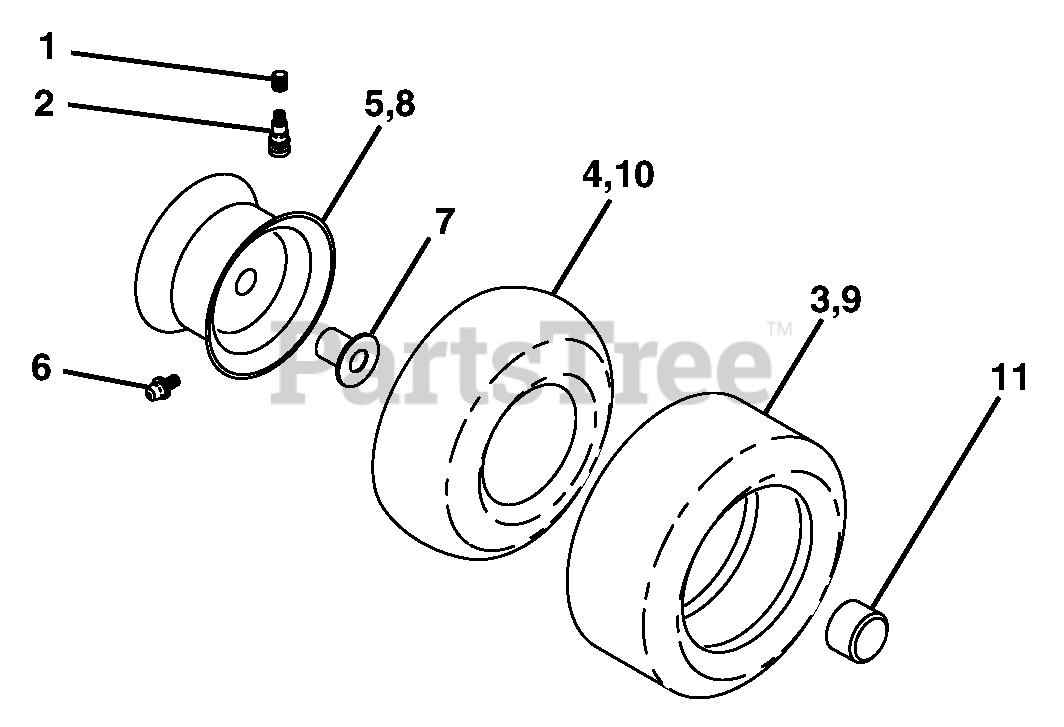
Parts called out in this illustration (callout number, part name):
1	Cap, Tire valve
2	Stem, Valve
4	Tube, Front
5	Rim assembly, 6"front
6	Fitting, Grease (Front wheel only)
7	Bearing, Flange (Front wheel only)
8	Rim assembly, 8" rear
9	Tire, Rear
10	Tube, Rear
11	Cap, Hub Axle
11	Sealant, Tire (10 oz. Tube)
